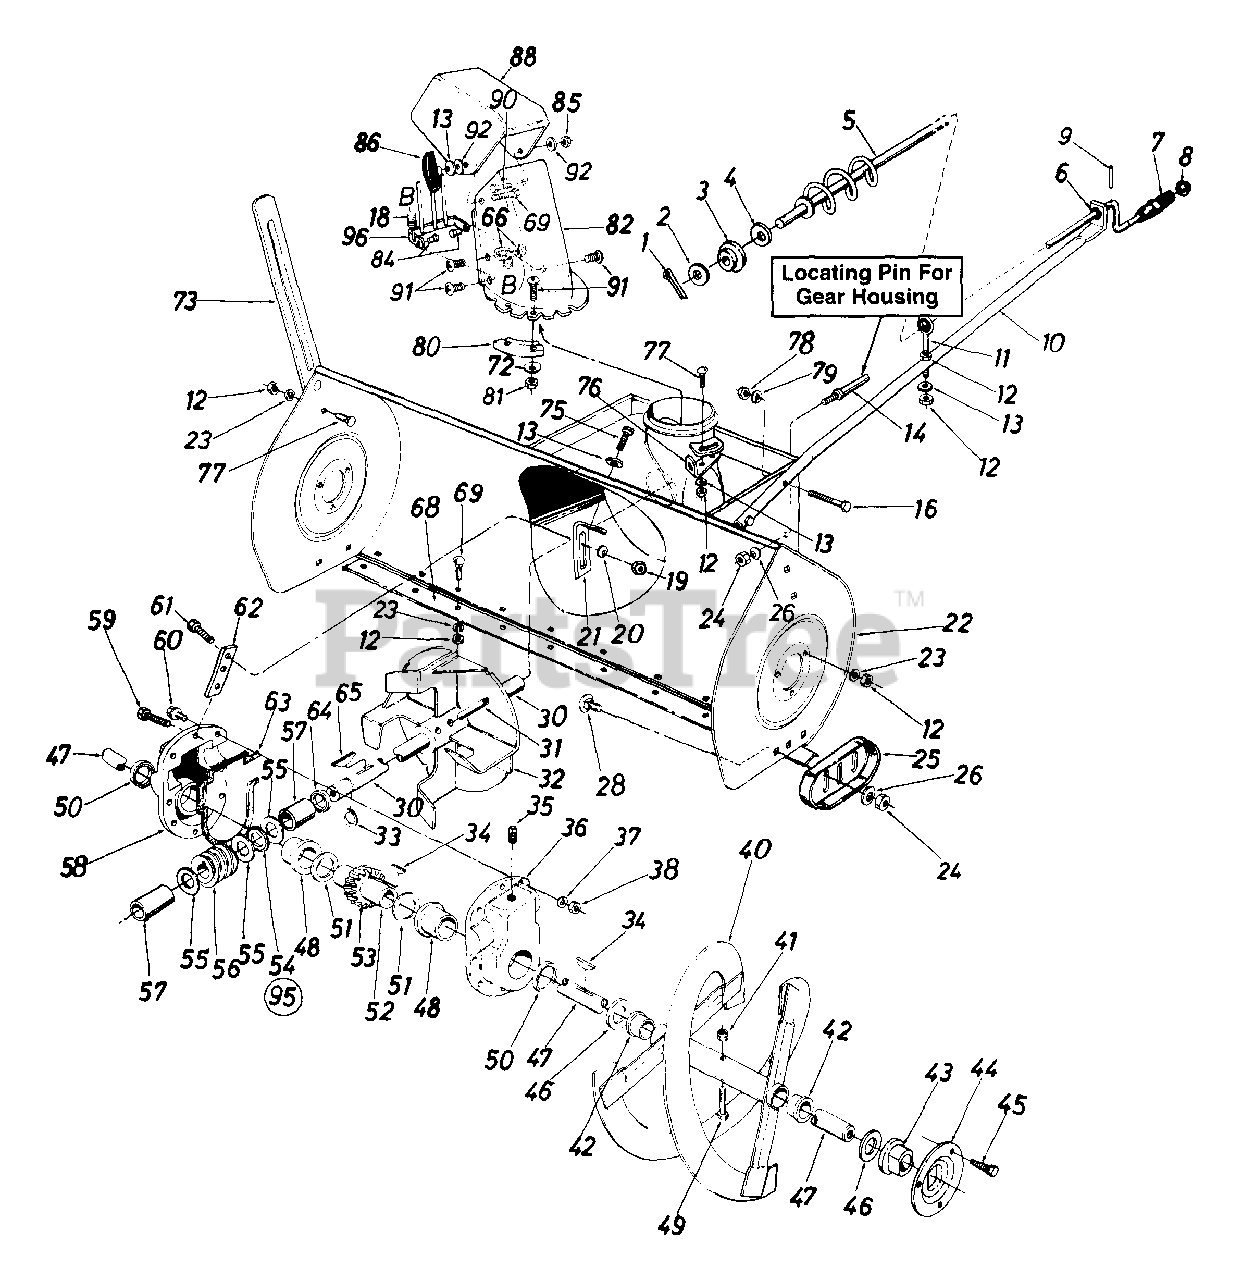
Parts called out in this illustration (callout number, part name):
1	Cotter Pin 3/32" x .75"
2	Fl-Wash. .385" I.D. x .62" O.D. x .06"
3	Plastic Bushing .380" I.D.
4	Fl-Wash. .385" I.D. x .62" O.D. x .06"
5	Chute Crank Ass'y.
6	Plastic Bushing .38" I.D.
7	Knob - Black
8	Cap Speed Nut 3/8" Rod
9	Spring Pin
10	Chute Crank Supporting Tube
11	Eyebolt Chute Crank Support
12	Hex Nut 5/16-18 Thd.
13	Bell-Wash. .345" I.D. x .88" O.D. x .06"
14	Belt Keeper Studs 3/8-16 x 2.75"
16	Hex Scr. 3/8-24 x 1.25 Lg.
18	Extension Spring
19	Hex Nut 1/4-28 Thd.
20	Bell-Wash. .25" I.D. x .88" O.D. x .062"
22	45" Snow Thrower Hsg. Ass'y.
23	L-Wash. 5/16" I.D.
24	Hex Jam Nut 3/8-16 Thd.
25	Reversible Slide Shoe
26	Bell-Wash. .4" I.D. x .88" O.D. x .06"
28	Carr. Bolt 3/8-16 x .62" Lg.
30	Blower Axle 14.75" Lg.
31	Spr. Spiral Pin - H.D.
34	#91 Woodruff Key 1/4" x 3/4" Dia.
35	Plastic Vented Plug 1/4-18 Pipe Thd.
36	Gear Hsg. Half - L.H.
37	Shakeproof Spr. Wash.
38	Hex Ins. L-Nut 5/16-18 Thd.
41	Hex Ins. L-Nut 5/16-18 Thd.
42	Flange Bearing
43	Flange Bearing w/ Flats
44	Bearing Housing
45	Hex Sems Bolt 5/16-18 x .75" Lg.
48	Flange Bearing
49	Shear Bolt 5/16-18 x 1.75
50	Oil Seal 1.5" I.D. Garlock
51	Fl-Wash. 1.5" I.D. x 2" O.D. x .03"
52	Worm Gear Shaft
53	Worm Wheel - L.H. Double Thd.
54	Thrust Brg. .88" I.D. x 1.44" O.D. x .078"
55	Fl-Wash. .88" I.D. x 1.4" O.D. x .125"
56	Worm Gear - L.H. Double Thd.
57	Sleeve Brg. .875" I.D.
58	Gear Hsg. Half - R.H.
59	Hex Bolt 5/16-18 x 1.25" Lg.
60	Hex Bolt 5/16 x 1" Lg.
61	Hex Bolt 1/4-28 x .75" Lg.
62	Gear Hsg. Support Plate
63	Cork & Rubber Gasket
64	Oil Seal for .875" I.D. Garlock
65	#9 Hi-Pro Key 3/16" x 3/4" Dia. - H.T.
66	Hex L-Nut 1/4-20 Thd.
69	Carr-Bolt 5/16-18 x 1" Lg.
72	Fl-Wash. .281" I.D. x .5" O.D. x .063"
73	Guide Blade
75	Hex AB-Tap Scr. 5/16 x .75" Lg.
77	Carr. Bolt 5/16-18 x .75" Lg.
78	Hex Nut 3/8-24 Thd.
79	L-Wash. 3/8" I.D.
80	Chute Flange Keeper
81	Hex L-Nut 1/4-20 Thd.
82	Lower Chute
84	Shld. Nut 1/4-20 Thd.
85	Hex L-Nut 5/16-18 Thd.
86	Hand Knob
88	Upper Chute
90	Truss Mach. Scr. 5/16-18 x .75" Lg.
91	Truss Mach. Scr. 1/4-20 x .5" Lg.
92	Fl-Wash. .344" I.D. x 1.125" O.D. x .125"
95	Gear Box Ass'y. Complete
